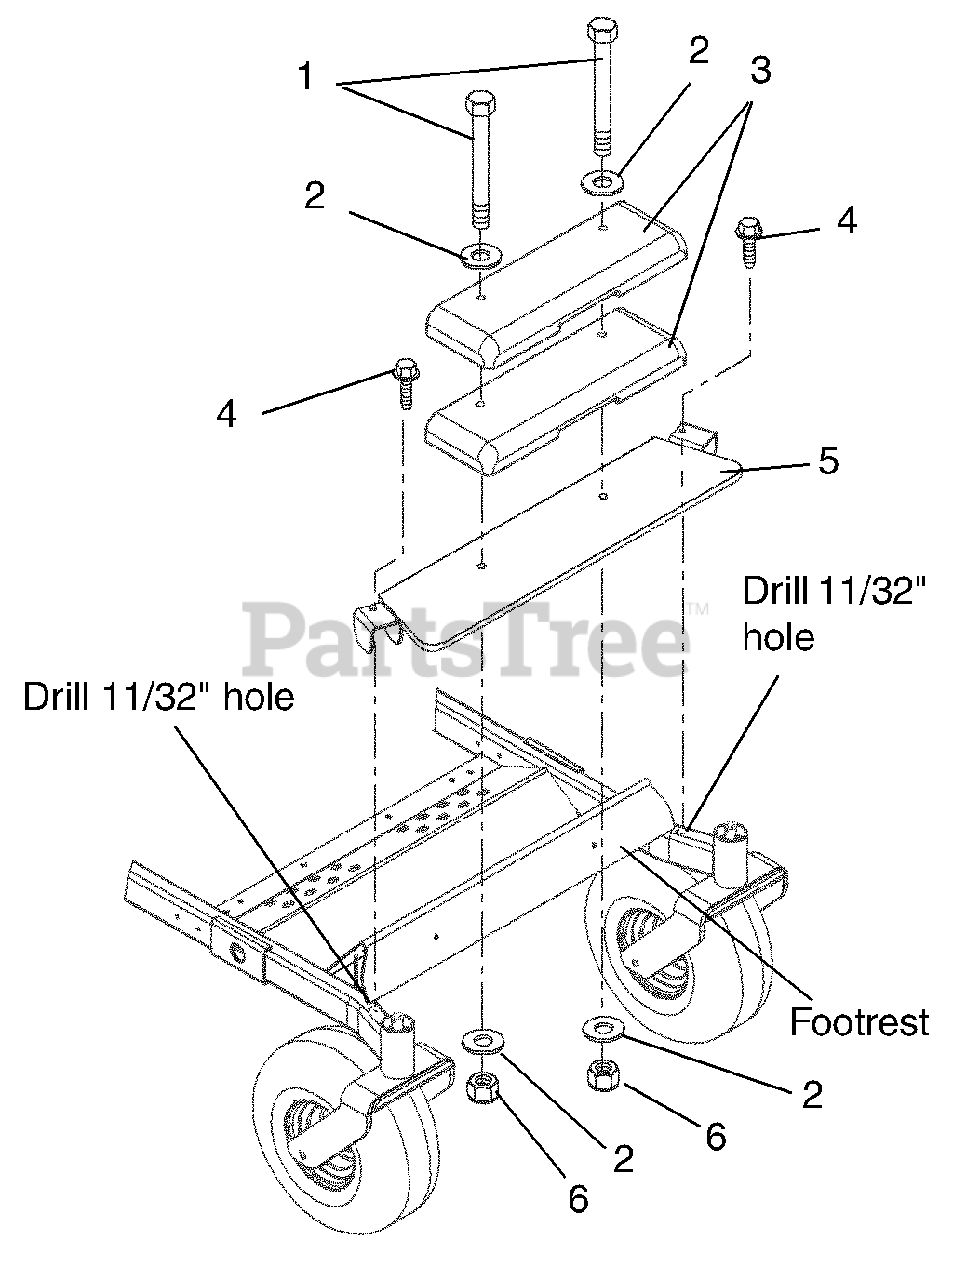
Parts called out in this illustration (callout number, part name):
1	Hex Bolt, 1/2"-13 x 5 1/2"
2	Flat Steel Washer, 1/2" x 1" x 1/16"
3	Counterweight
4	Tapping Screw, 3/8"-16 x 1/2"
5	Counterweight Bracket
6	Nylon Lock Nut, 1/2"-13
